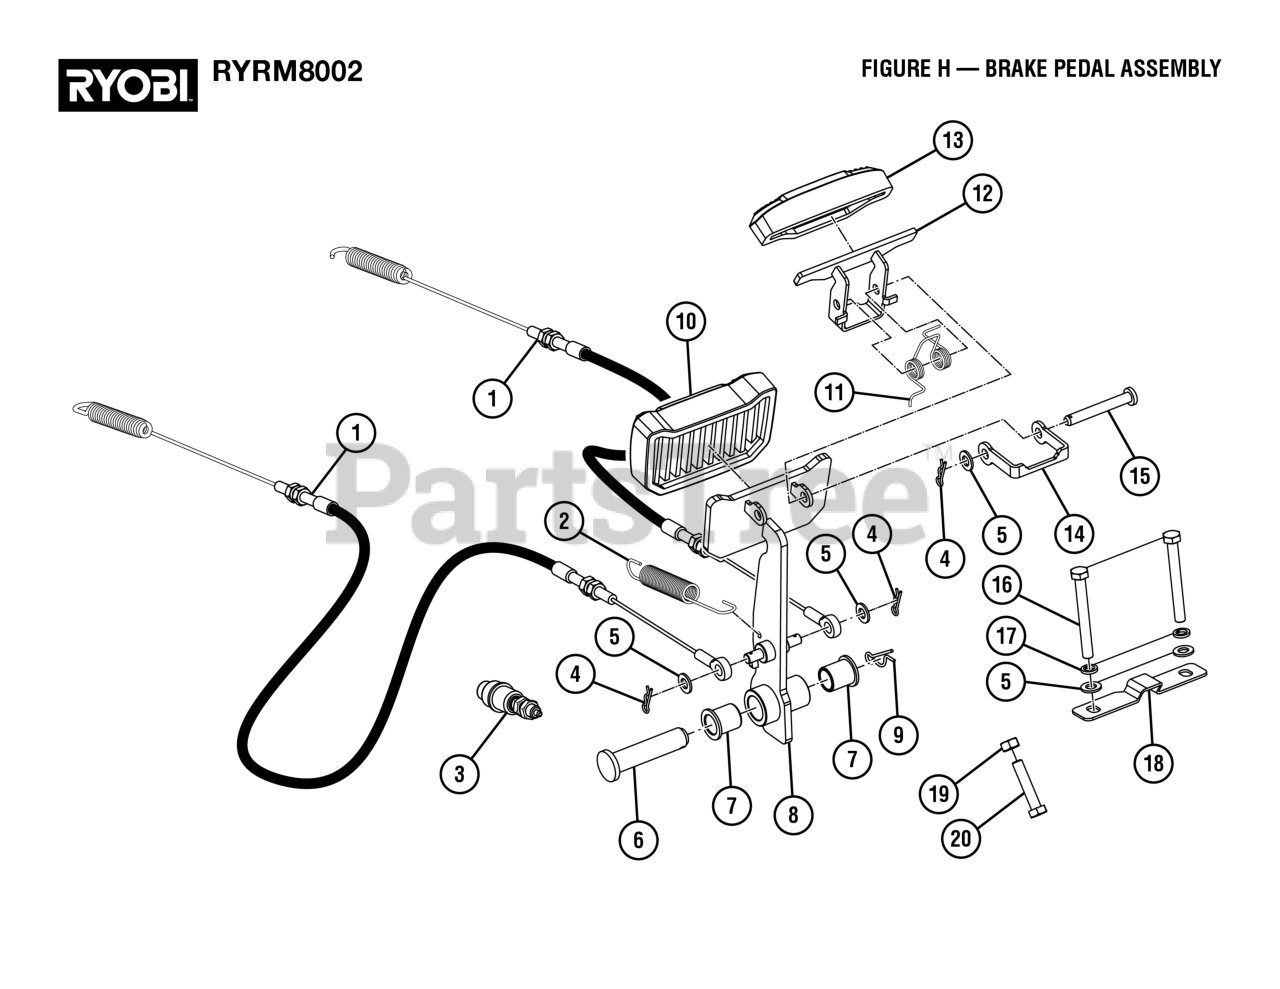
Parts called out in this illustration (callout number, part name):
1	Brake Cable
2	Brake Pedal Spring
3	Brake Switch Assembly
4	Cotter Pin (8 mm)
5	Washer (OD16 x ID8.4 x 1.6t)
6	Clevis Pin
8	Brake Pedal Lever
9	Lock Pin (16 mm)
10	Brake Pedal Rubber Pad
11	Parking Brake Torsion Spring
12	Parking Brake Pedal
13	Parking Brake Rubber Pad
14	Parking Brake Latch
15	Clevis Pin (M8 x 60 mm)
16	Bolt (M8 x 70 mm, Hex Hd.)
17	Lock Washer (OD9.8 x ID8.5 x 5t)
18	Brake Latch Hook
19	Hex Nut (M8)
20	Bolt (M8 x 40 mm, Hex Hd.)
